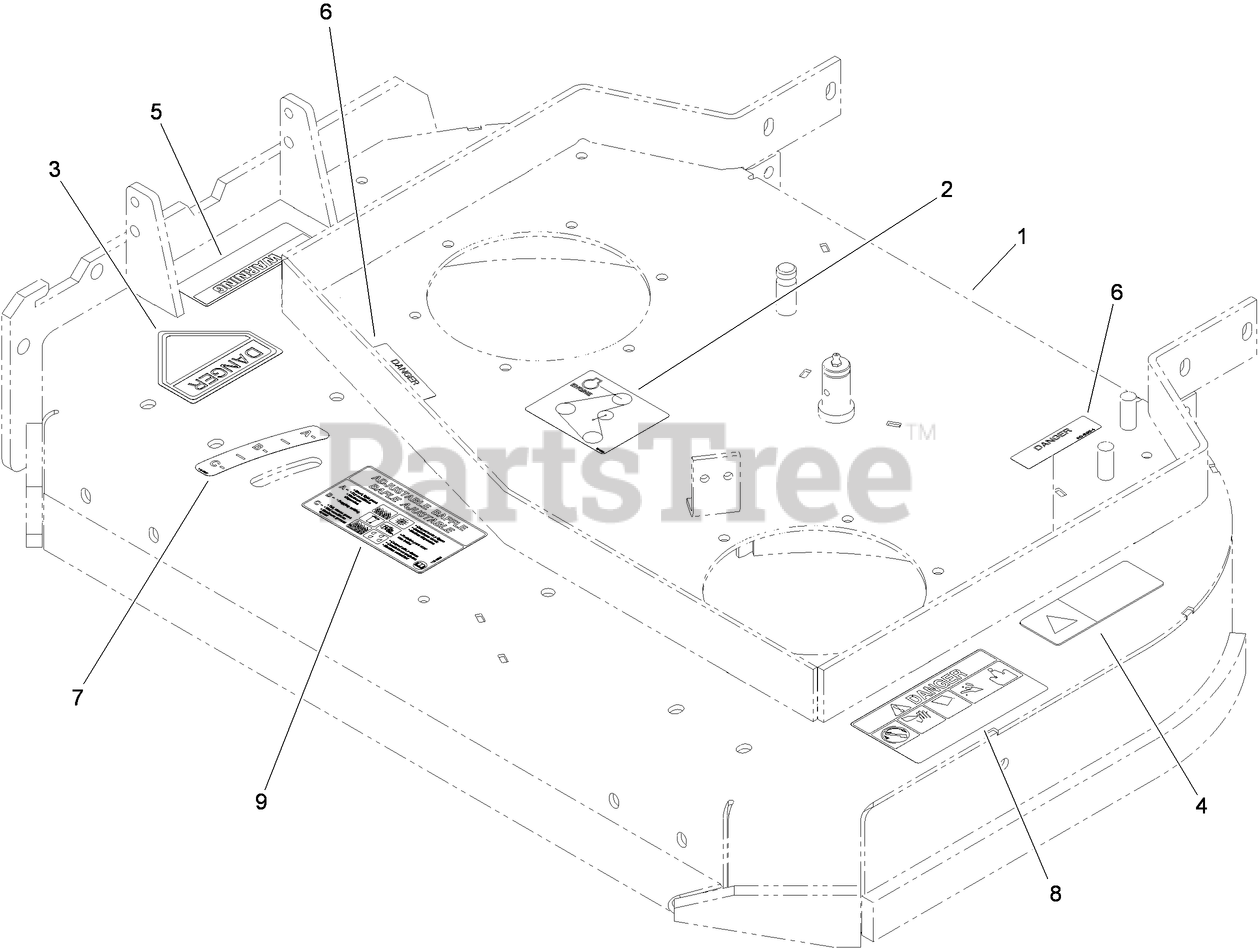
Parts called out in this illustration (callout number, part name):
1	36 INCH DECK ASM
2	DECAL-ROUTING, BELT
3	DECAL-DANGER
4	DECAL-TORQUE, BOLT
5	DECAL-WARNING
6	DECAL-COVER, MISSING
7	DECAL-SETTING, BAFFLE
8	DECAL-DANGER, THROWN OBJECT
9	DECAL-ADJUSTMENT, BAFFLE
